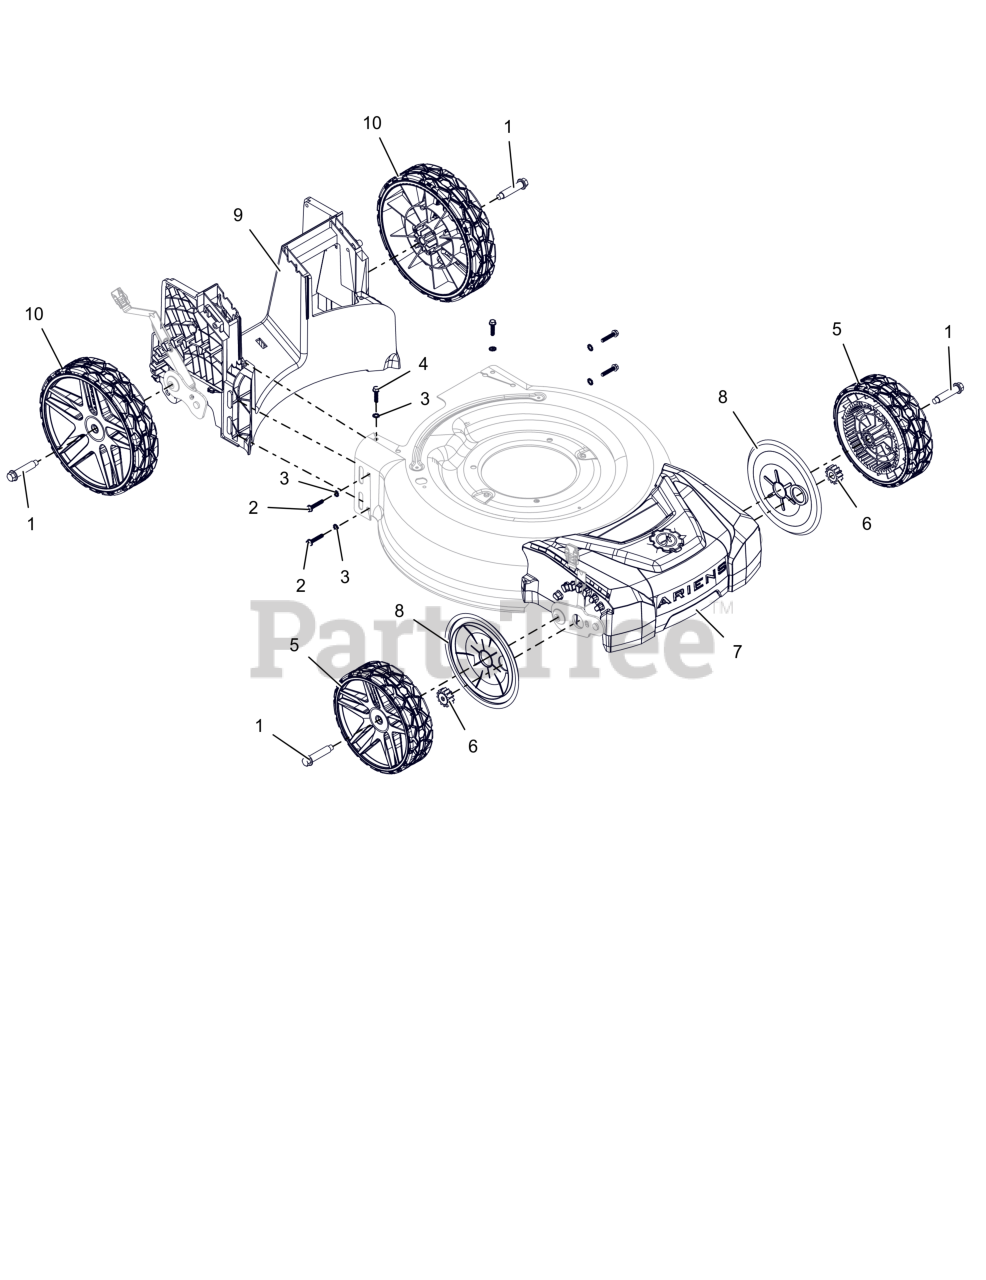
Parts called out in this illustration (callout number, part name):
1	BLT, SHLDR HWH .325X1.981X 3/8-16
2	SCR, HI-LO HWH 1/4-15 X 1.25
3	WSHR-LK-EXT, .256X.510X.028
4	SCR, HI-LO HWH 1/4-15 X 1.00
5	WHEEL, MOLDED GEAR 8"
6	GEAR, FWD SPUR
7	COVER, FRONT
8	COVER, DUST - 8"
9	BAFFLE, FWD
10	WHEEL, 10" - DARK GRAY
